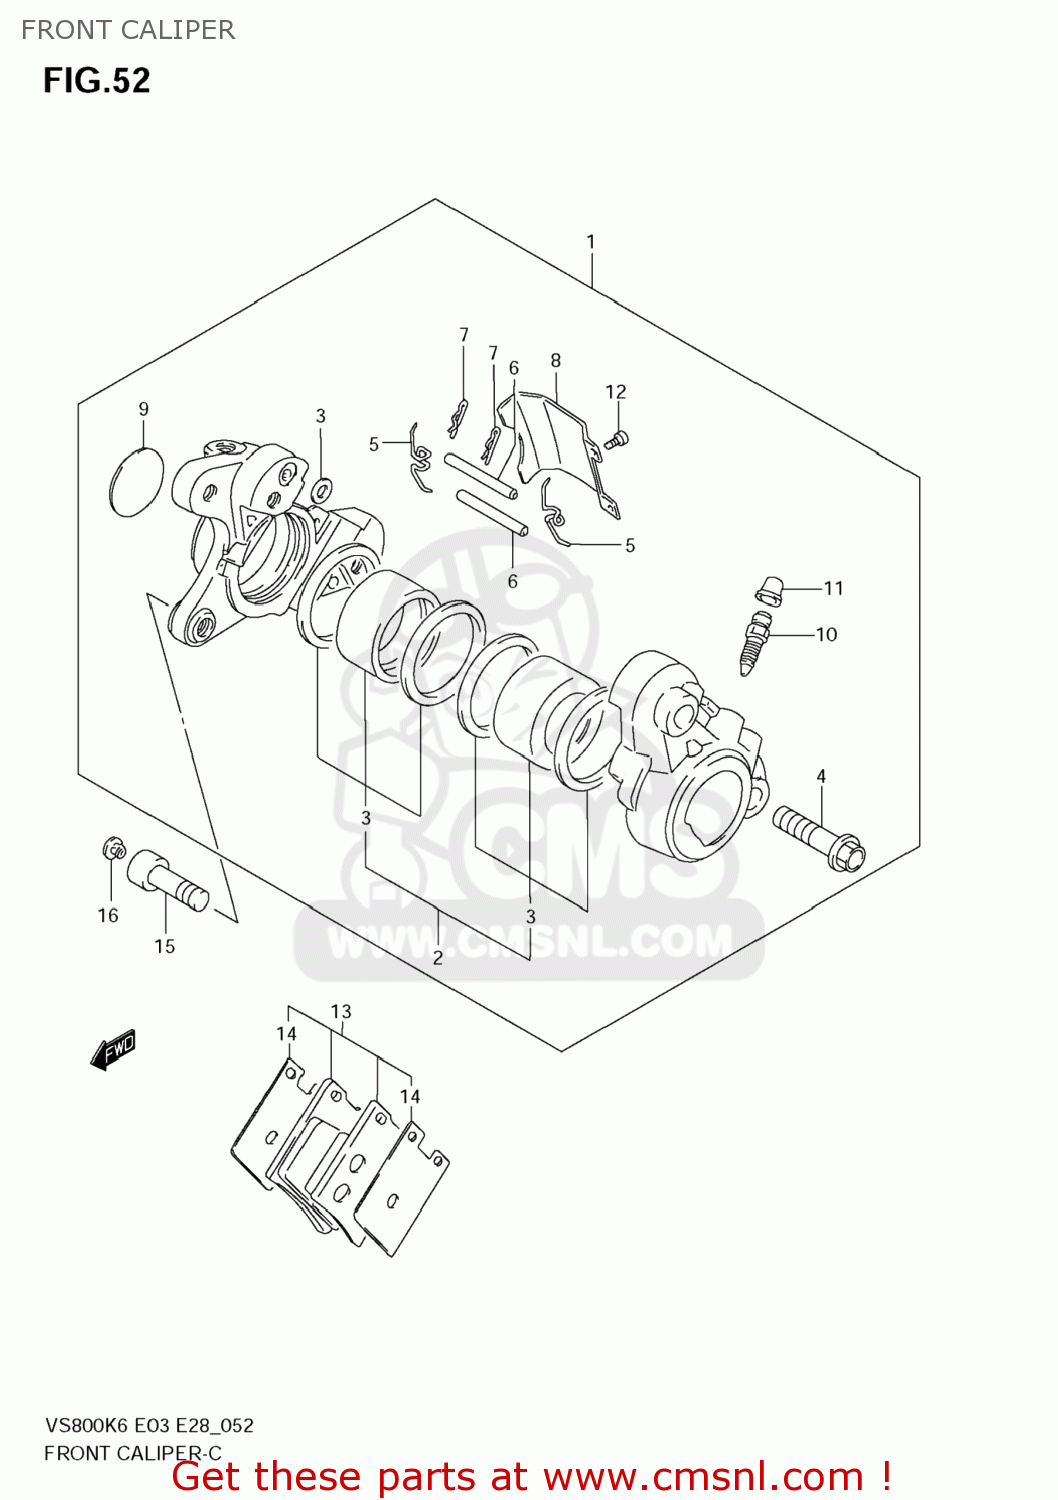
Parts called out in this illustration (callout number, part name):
1	CALIPER ASSY,FR
2	PISTON SET
3	SEAL SET,PISTON
4	BOLT,HOUSING
5	SPRING
6	PIN,PAD
7	CLIP,PAD PIN
8	COVER,CALIPER HOUSING,DUST
9	CAP,CALIPER
10	BLEEDER
11	CAP,BLEEDER PLUG
12	SCREW,CALIPER COVER(4X6)
13	PAD & SHIM SET (NAS)
14	SHIM,PAD
15	BOLT(10X33)
16	CAP(OD:12)
